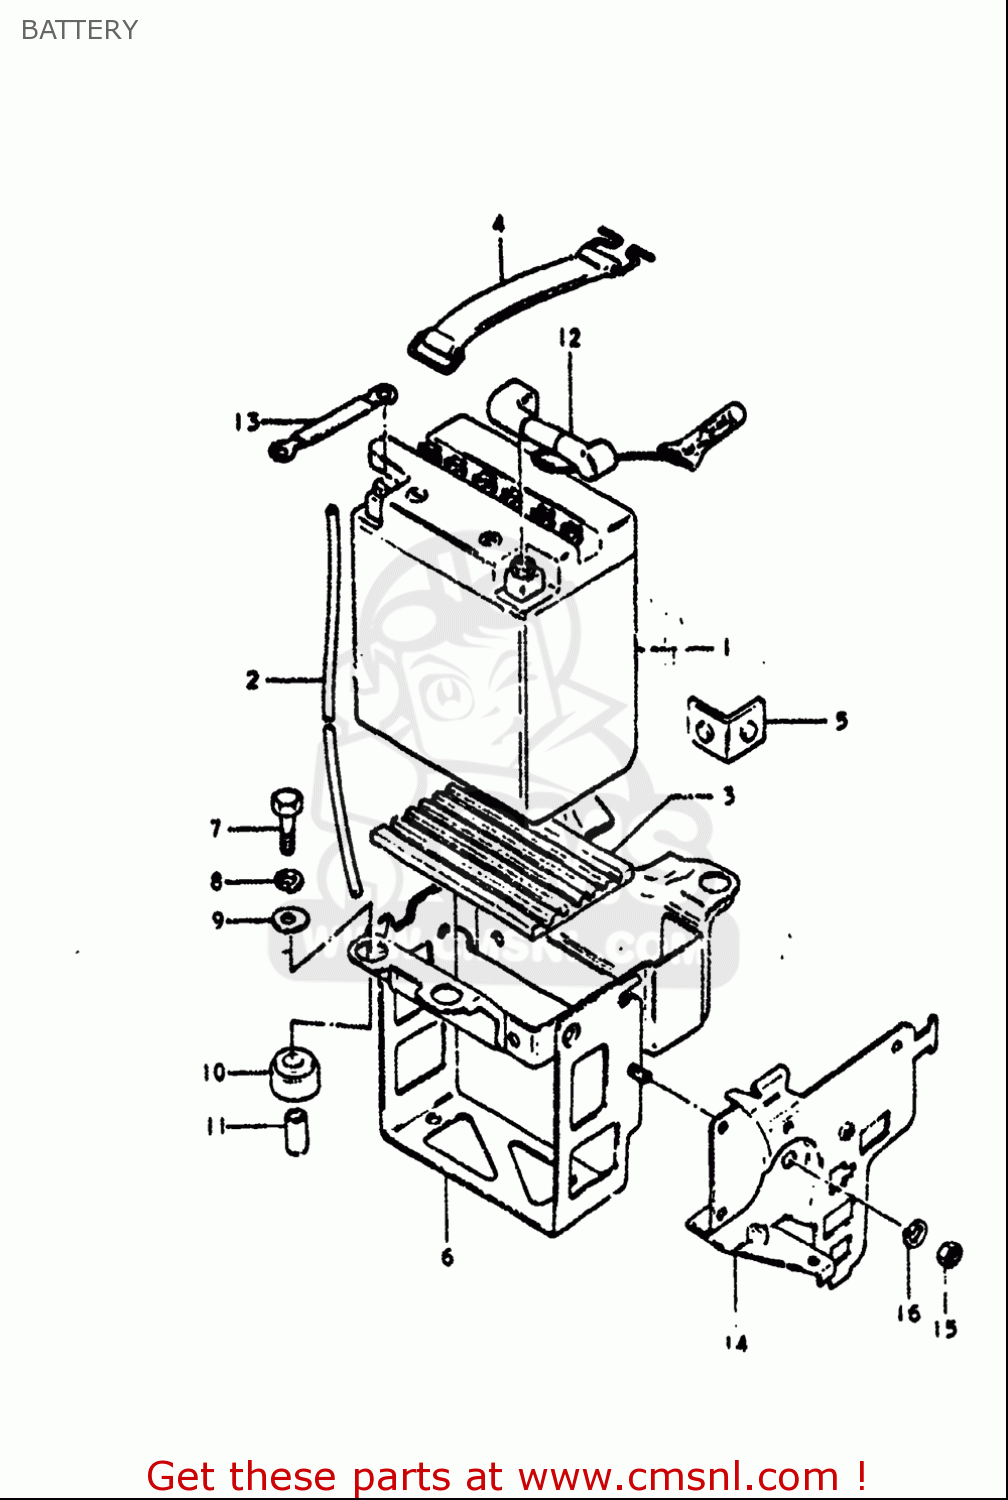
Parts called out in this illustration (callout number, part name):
1	BATTERY ASSY (12V)
2	HOSE,BATTERY EXHAUST(L:780)
3	PROTECTOR,BATTERY
4	BAND
5	PROTECTOR(80X80X2)
7	BOLT
8	WASHER,LOCK
9	WASHER(6.5X18X1.6)
10	CUSHION
11	SPACER(6.1X8X15.5)
12	LEAD WIRE,BATTERY PLUS
13	WIRE,ENGINE EARTH
15	NUT
16	WASHER,LOCK
